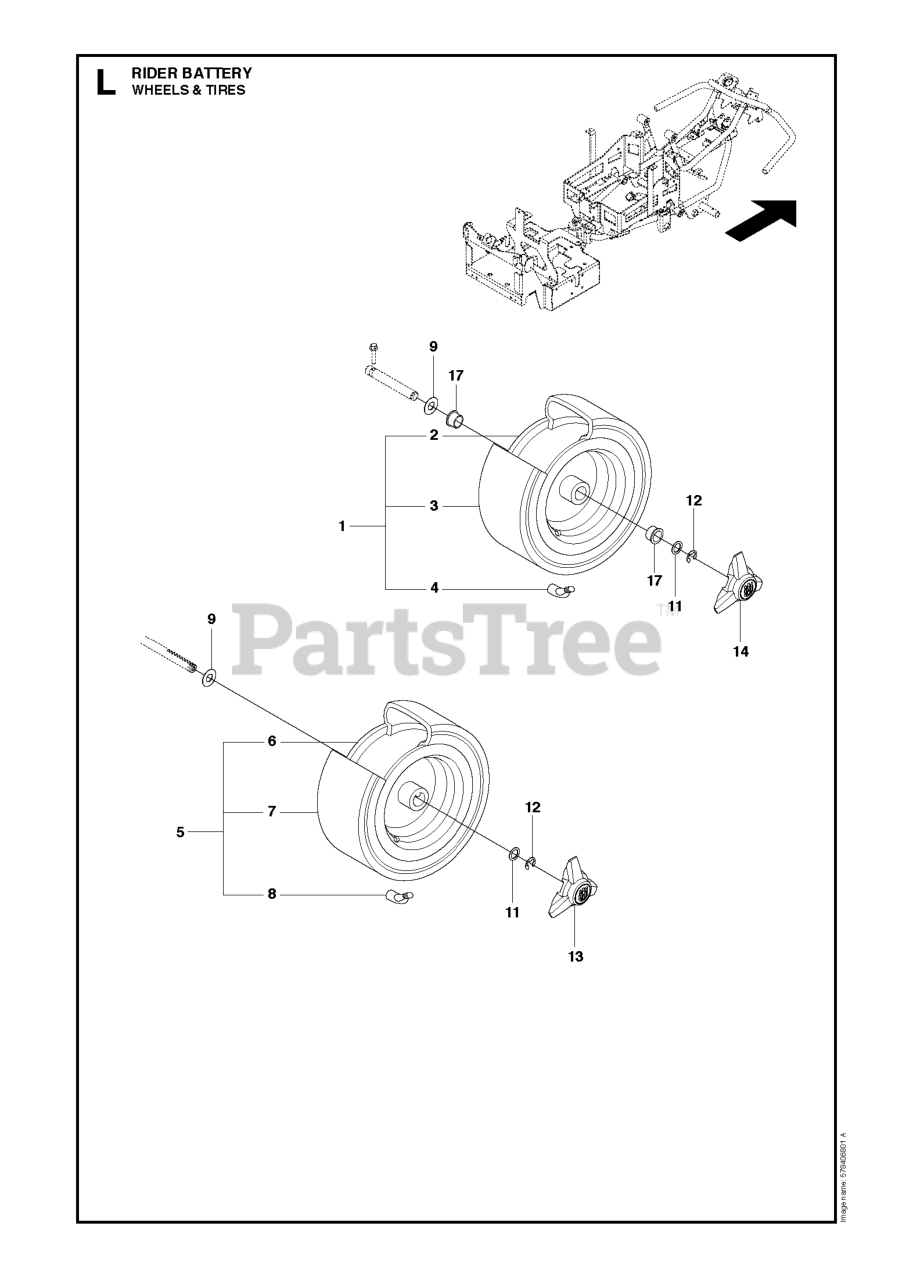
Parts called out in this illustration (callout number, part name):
4	VALVE
8	VALVE
12	RETAINING RING
